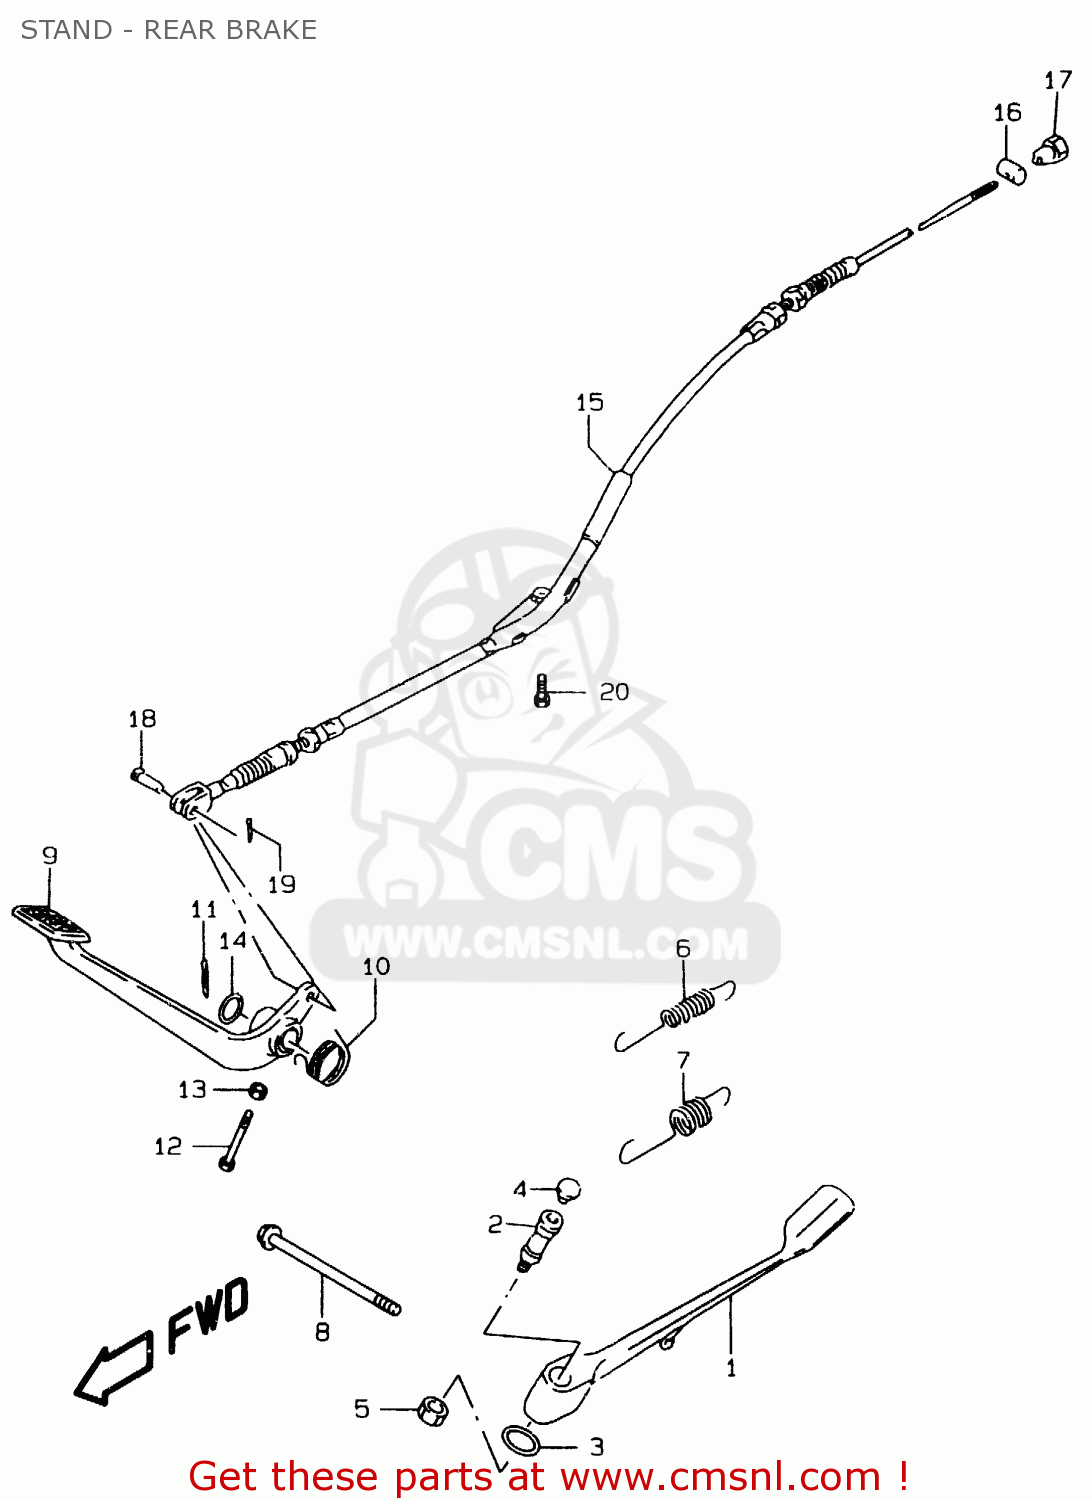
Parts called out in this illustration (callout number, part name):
1	STAND,PROP
2	BOLT,PROP STAND
3	THRUST WASHER
4	CAP,PROP STAND BOLT
5	NUT
6	SPRING
7	SPRING
8	BOLT(10X105)
9	PEDAL,BRAKE
10	SPRING
11	COTTER PIN
12	BOLT(6X31)
13	NUT 6MM
14	WASHER(16.5X22X1)
15	CABLE,RR BRAKE
16	PIN(13X18)
17	NUT
18	PIN(L:17.5)
19	PIN
20	BOLT
